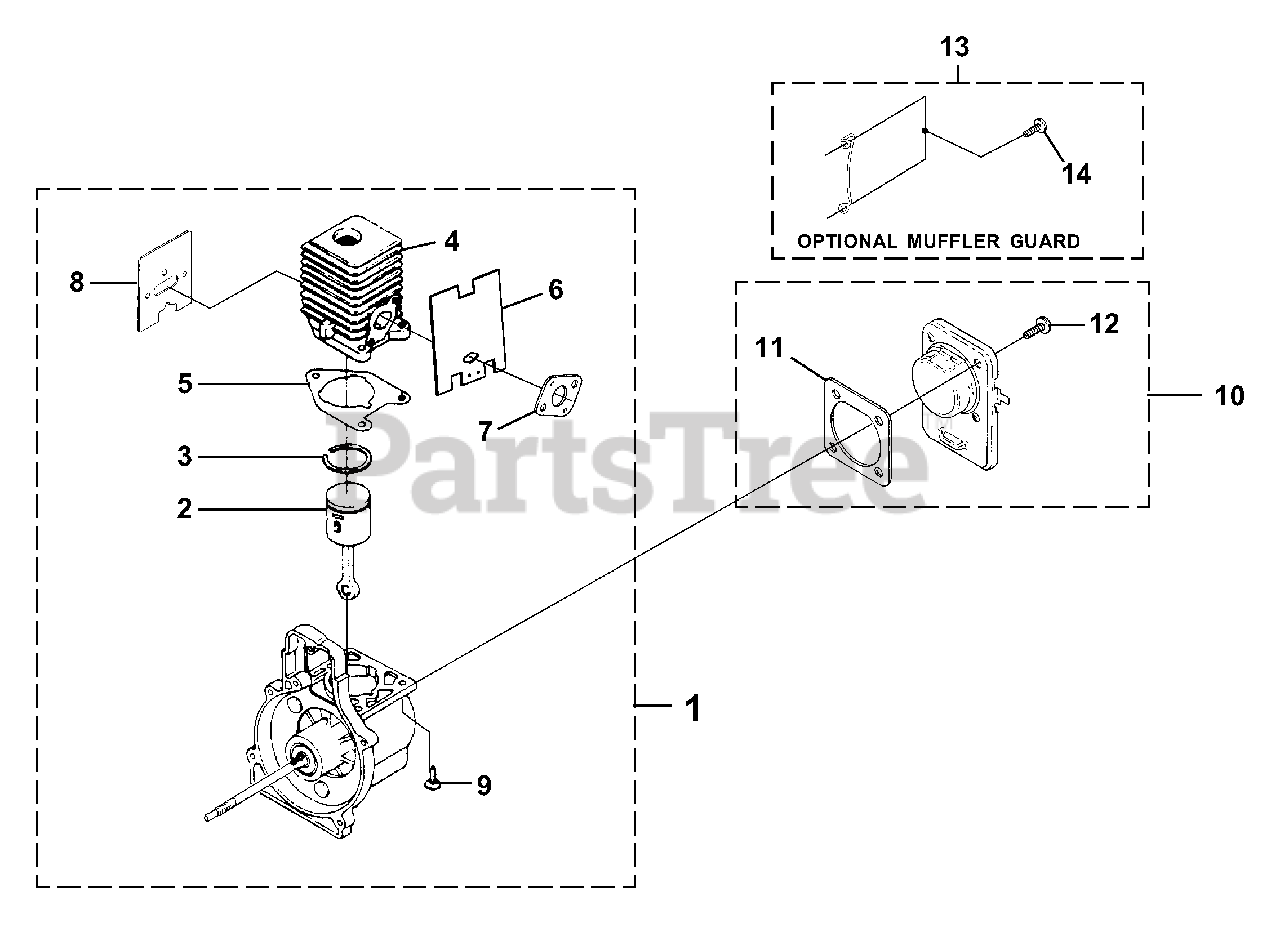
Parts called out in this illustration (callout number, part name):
1	SHORT BLOCK
2	PISTON & ROD ASSY.
3	RING-Piston
4	CYLINDER ASSY.
5	GASKET-Cylinder
6	GASKET-Heat Dam
7	GASKET-Carburetor
8	GASKET-Muffler
9	SCREW-Sems (12-24 X 3/4")
10	CRANKCASE COVER ASSEMBLY
11	GASKET-Crankcase Cover
12	SCREW-Sems (10-24 X 1/2")
13	MUFFLER GUARD
14	SCREW-Plastite (10-14 X 1/2")
